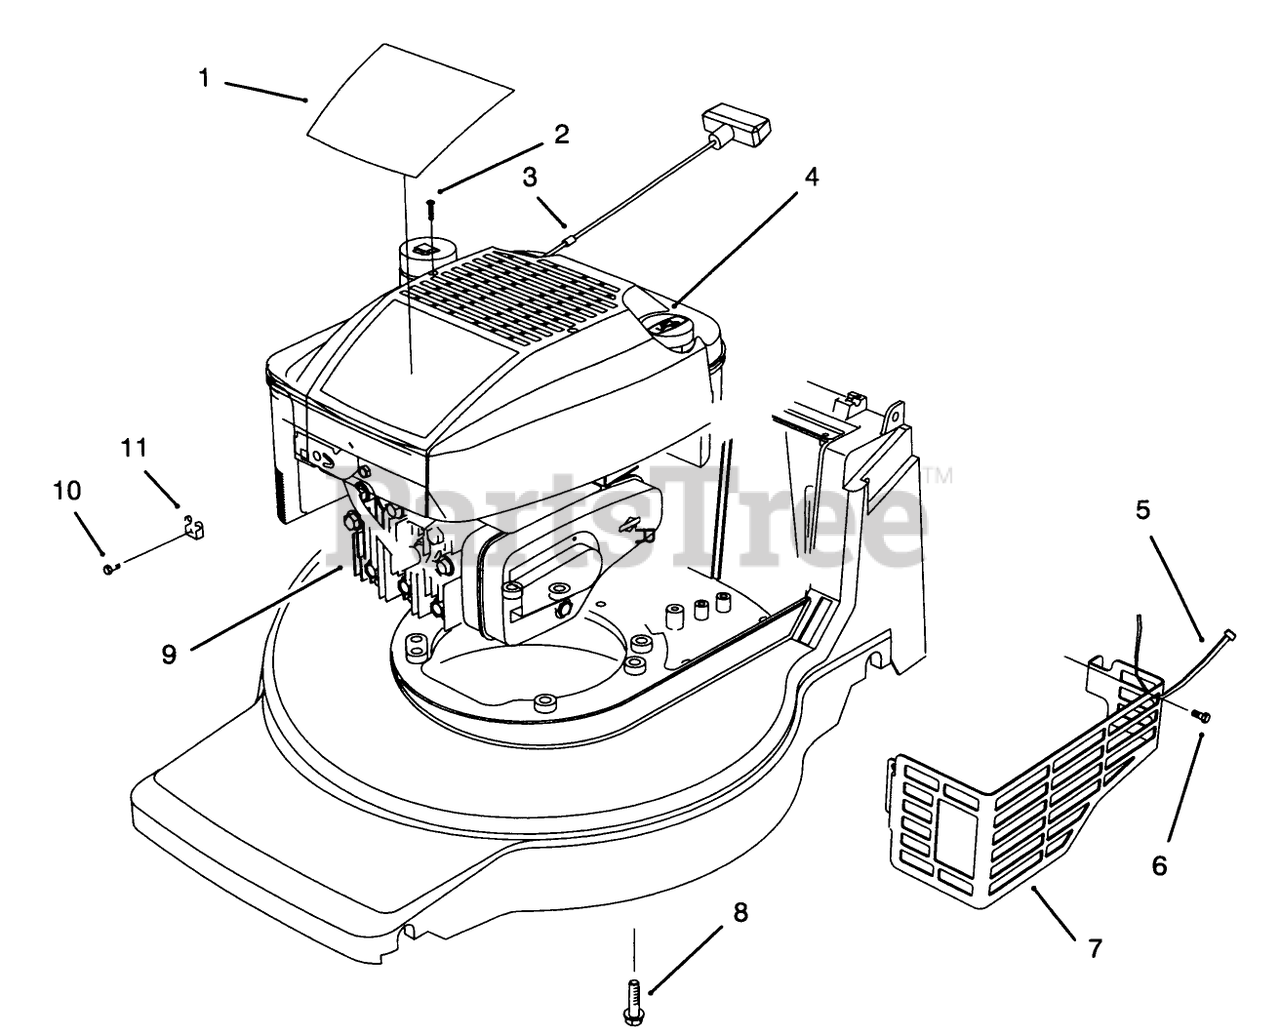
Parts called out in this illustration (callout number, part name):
1	DECAL - ENGINE
2	SHROUD SCREW F/W
3	STOP-ROPE
4	ENG SHROUD F/W
5	TIE-CABLE
6	SCREW-HWH
7	SHIELD - MUFFLER
8	SCREW-HWH
10	CLAMP SCREW F/W ENGINE
11	CLAMP-CASING
